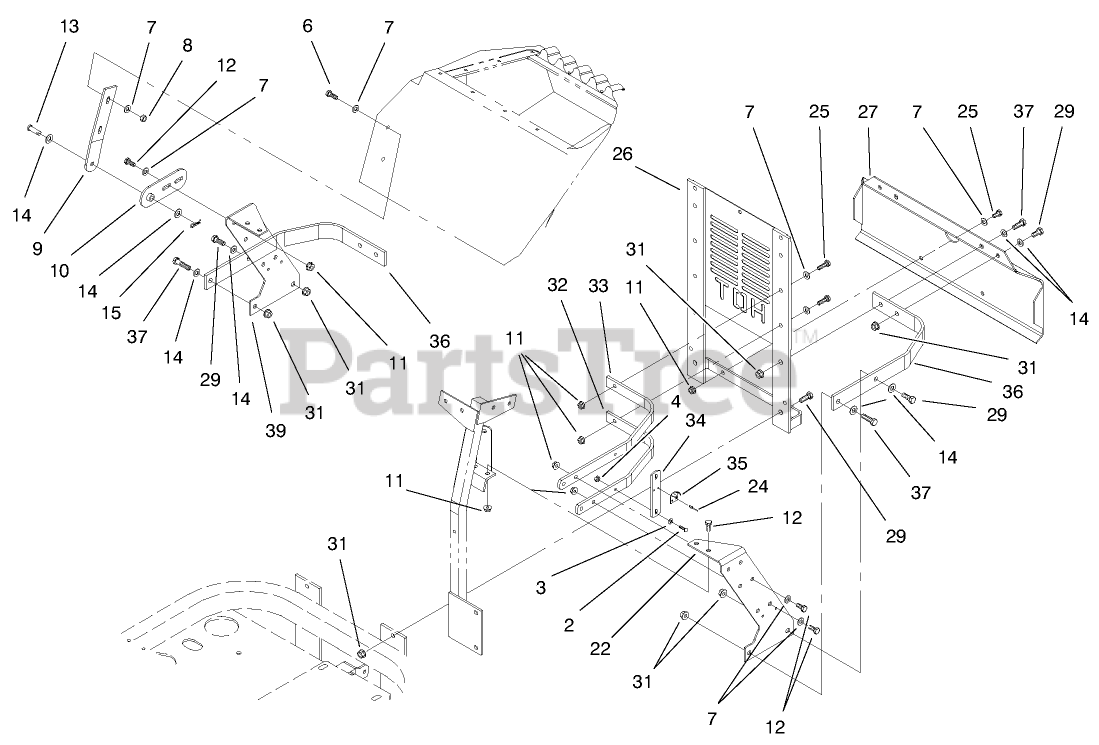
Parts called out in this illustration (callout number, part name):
2	Screw-HSBH
3	WASHER-FLAT
4	Nut
6	SCREW-HH
7	WASHER-PLAIN
8	NUT-LOCK NI
9	Plate-Hinge, Hood
10	Shackle Hinge ASM
11	NUT-HF
12	SCREW-HH
13	Pin-Clevis
14	WASHER-FLAT
15	Pin-Hair Cotter
22	Plate-Mount, Radiator
24	Rivet
25	SCREW-HH
26	Rear Radiator Mount ASM
27	Bumper-Rear
29	SCREW-HH
31	NUT-HHF, WHIZ
32	Rib-Top
33	Rib-Bottom
34	Bar-Hook, Latch
35	Keeper-Latch, Rubber
36	Bar-Frame, Radiator Mount
37	SCREW-HH
39	Plate-Mount, Radiator
